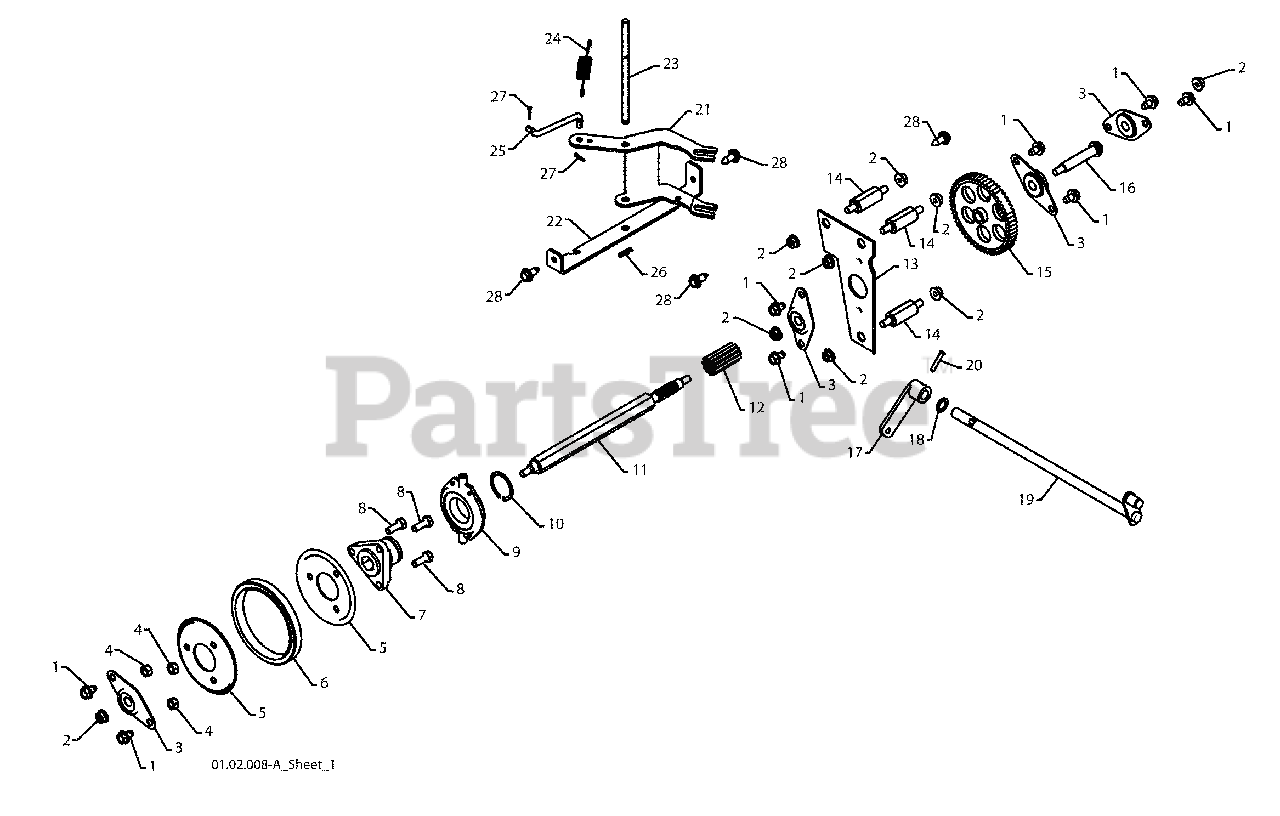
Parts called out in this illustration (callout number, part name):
1	BOLT 5/16--18 X .500
2	NUT 5/16--18
3	FLANGE BEARING
4	NUT 5/16--18
5	RUBBER WHEEL PLATE
6	RUBBER WHEEL RING
7	RUBBER WHEEL HUB
8	BOLT 5/16--18 X .875
9	TRUNNION BEARING ASSEMBLY
10	RETAINER
12	PINION GEAR
13	AUXILIARY PLATE
14	SPACER PLATE
15	INTERMEDIATE GEAR
16	AUXILIARY SHAFT
17	CONTROL ARM
19	CONTROL SHAFT ASSEMBLY
20	CLEVIS PIN
21	SHIFTER LEVER
22	PIVOT BRACKET
25	SHIFTER LINK
28	BOLT 5/16--18 x .750
